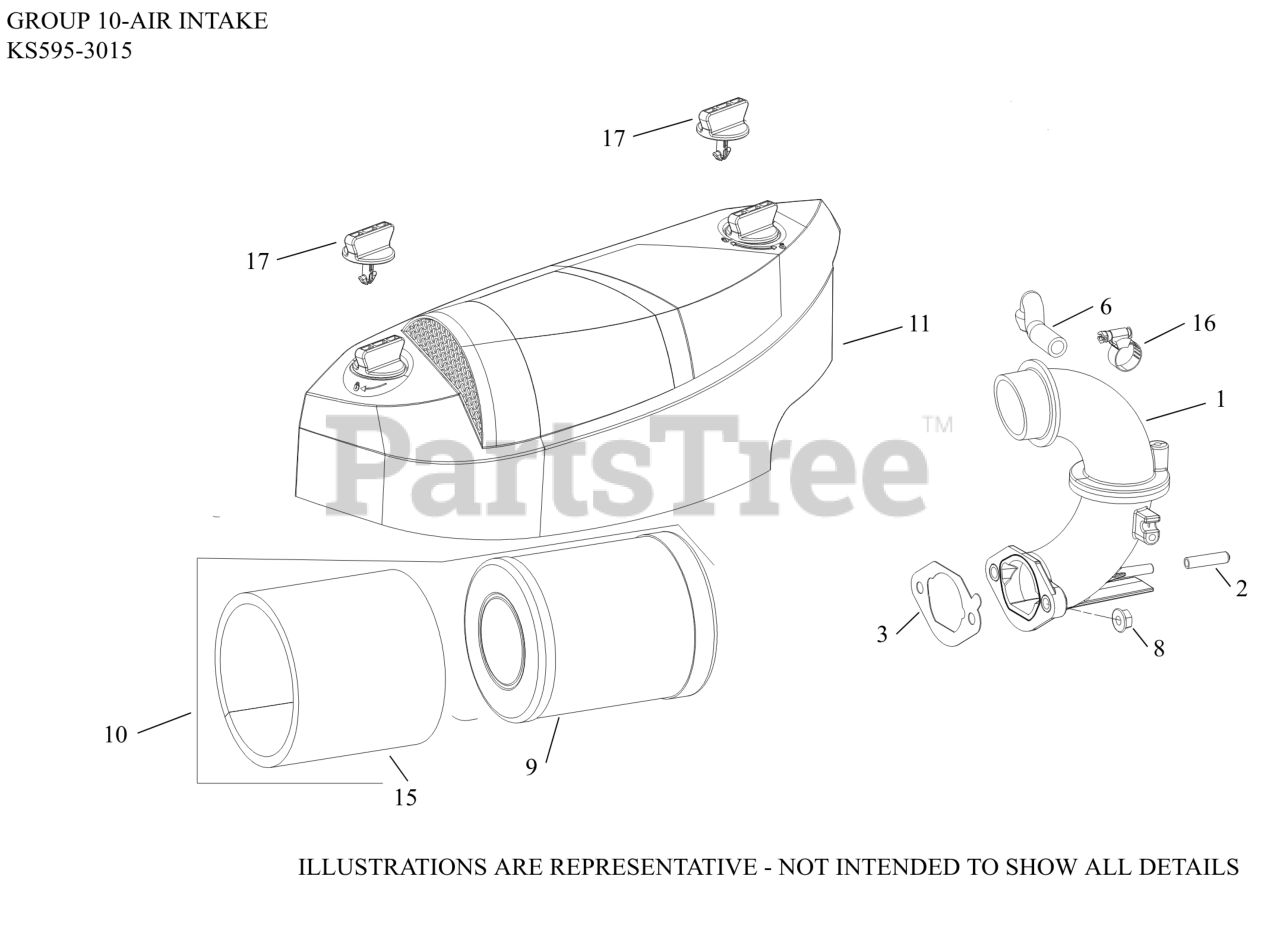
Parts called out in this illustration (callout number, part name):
1	ADAPTER, AIR CLEANER ASSY
2	CAP, MASKING
3	GASKET, CARBURETOR
6	HOSE, BREATHER
8	NUT, FLG M6X1.0
9	ELEMENT, AIR FILTER
10	AIR FILTER KIT (PRO)
11	COVER, AIR CLEANER ASSEMBLY (PRO)
15	ELEMENT, PRE-CLEANER
16	CLAMP, HOSE (KM)-USE 25 237 31-S
17	KNOB, AIR CLEANER COVER
